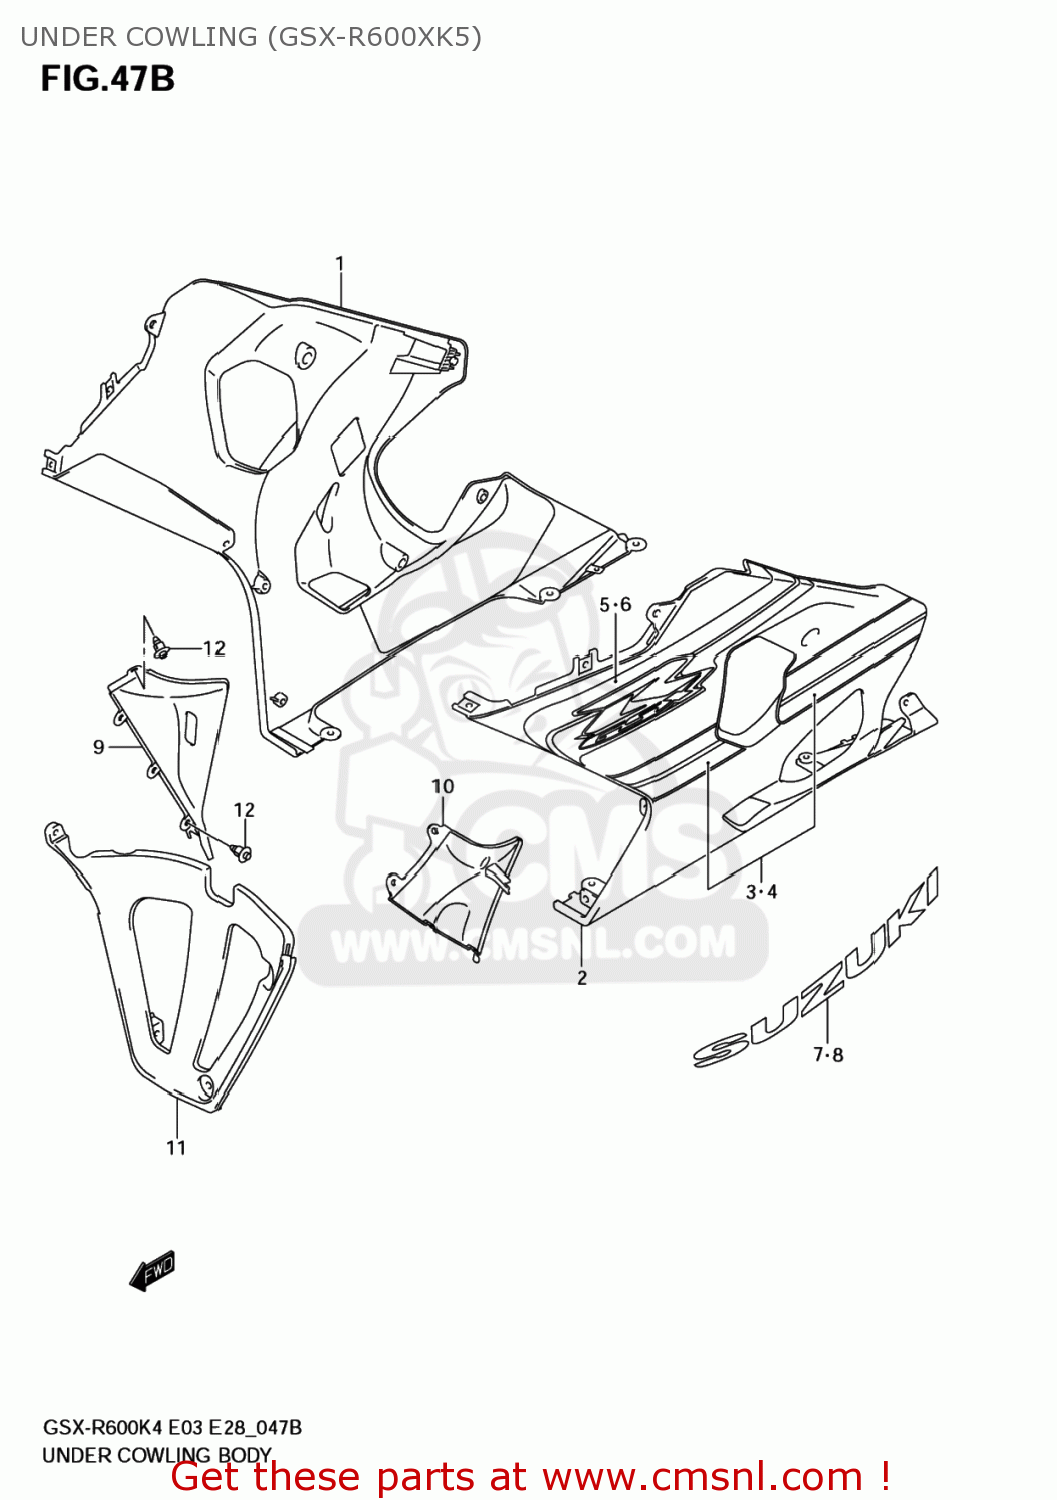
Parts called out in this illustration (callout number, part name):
1	COWLING ASSY,UNDER,R
2	COWLING ASSY,UNDER,L
3	TAPE SET,UNDER COWLING,R
4	TAPE SET,UNDER COWLING,L
5	TAPE,UNDER COWL,R
6	TAPE,UNDER COWL,L
7	EMBLEM,R
8	EMBLEM,L
9	COWLING,UNDER INNER,R
10	COWLING,UNDER INNER,L
11	COWLING,UNDER CTR
12	CLIP(BLACK)
